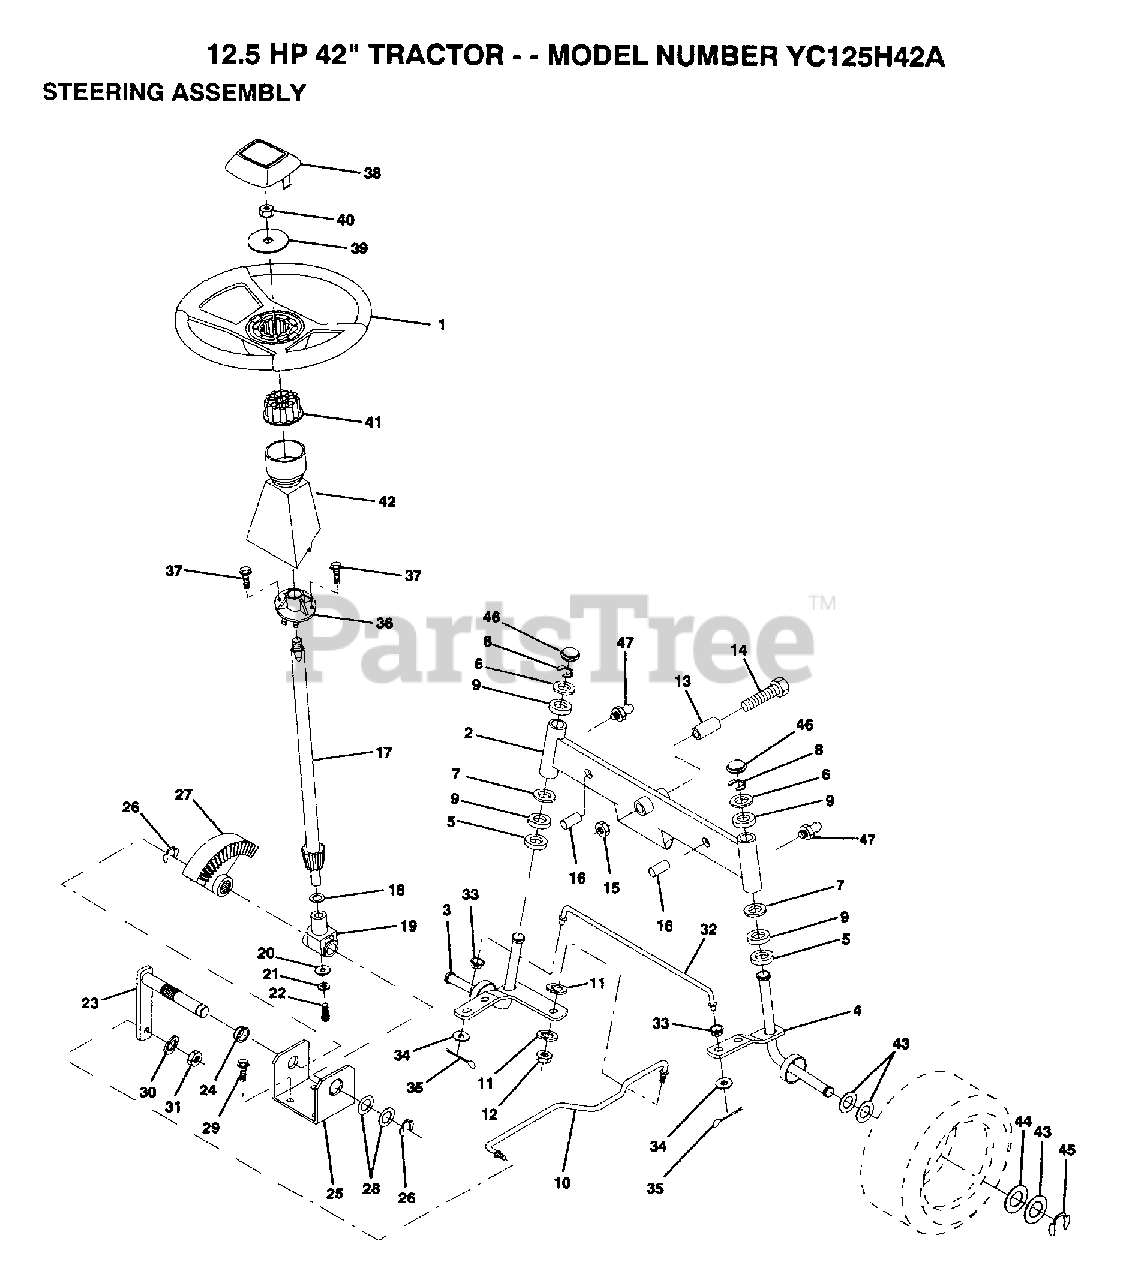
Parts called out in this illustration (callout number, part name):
3	SPINDLE LH
4	SPINDLE RH
5	WASHER .T
6	WASHER
7	WASHER
8	RING
9	COL. SRTG. BEAR.
11	LOCKWASHER
13	BEARING
14	BOLT HEX 5/8-11
15	"NUT-LOC,FLANGE LT"
16	AXLE PIN
17	SHAFT ASM
18	THRUST WASHER
19	SUPPORT.SHAFT
21	LOCKWASHER
22	"SCREW,SPECIAL"
24	NYLINER T
25	"BRKT,STEERING"
26	RING
27	GEAR SECTOR
28	WASHER .T
29	SCREW
30	LOCKWASHER
32	TIE ROD
33	BUSHING.DRAGLINK
34	WASHER
35	COTTER PIN
38	INSERT STEERING
39	WASHER T
40	GRIPCO NUT
41	ADAPTER-WHEEL LT
42	"TUBE, STR SHAFT"
43	WASHER
44	WASHER
45	RING
46	CAP
47	ZERK M
